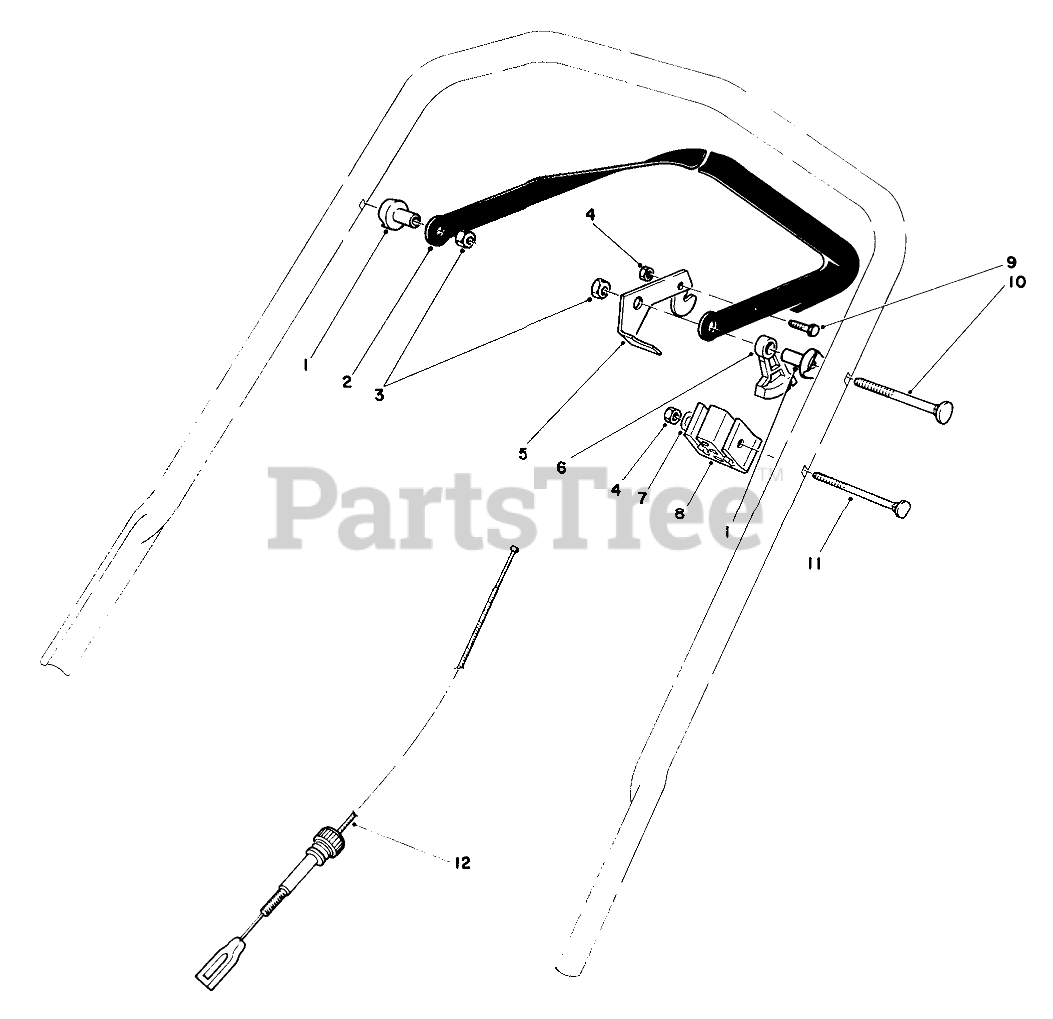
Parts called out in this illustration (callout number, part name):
1	SPACER-SUPPORT
2	Bar-Control
3	NUT-LOCK, NI
5	CONTROL LEVER
6	LEVER-TRACTION
7	WASHER-FLAT
8	SUPPORT-CABLE
9	SCREW-HH
10	5/16-18 X 2 HNDLE SCREW
11	SCREW-HANDLE
12	CABLE-TRACTION
